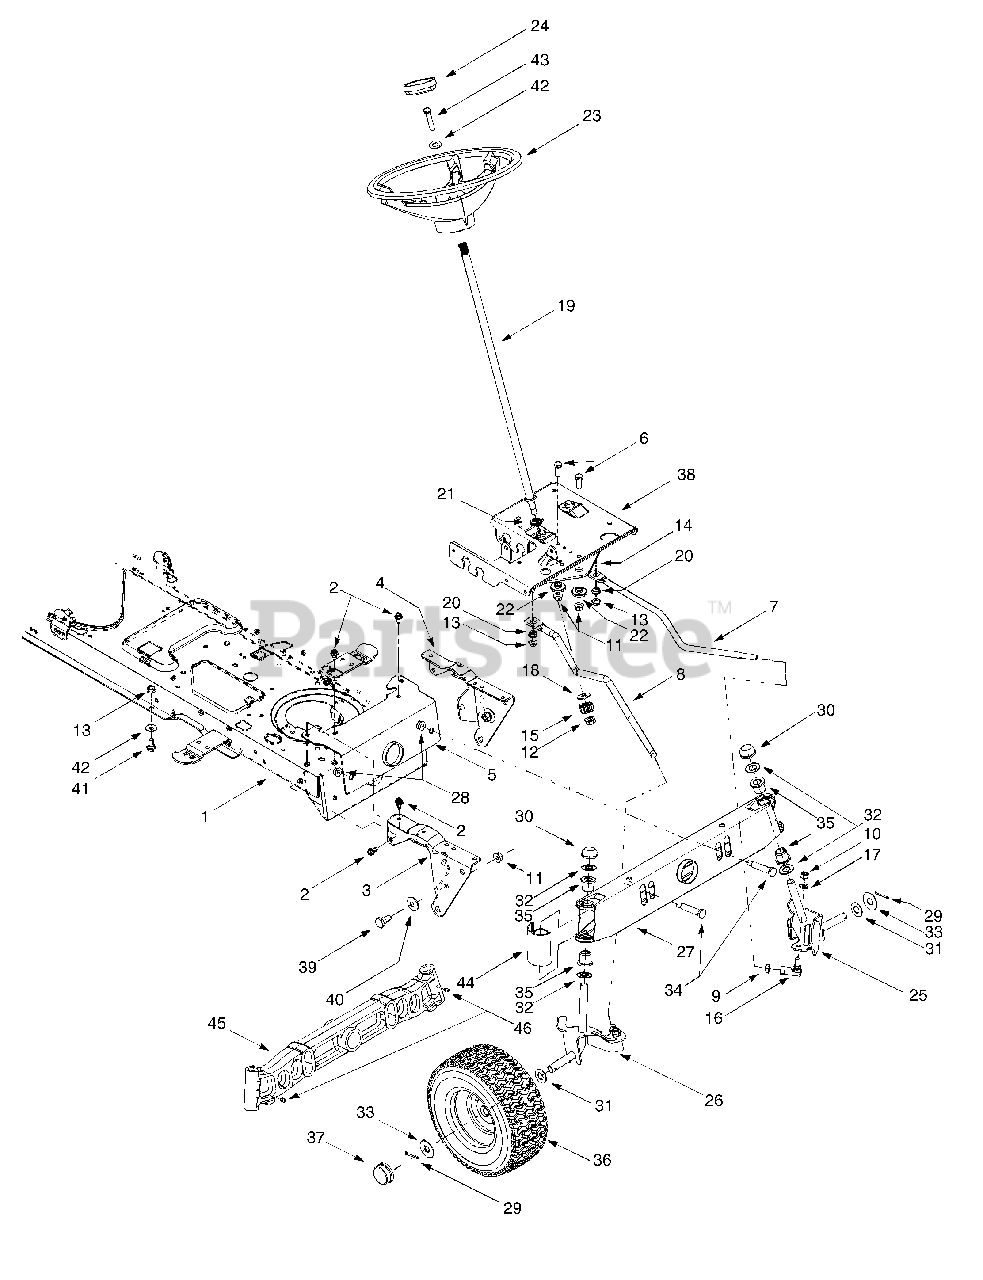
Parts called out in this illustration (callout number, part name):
6	Hex Cap Screw, 3/8-16 x 1 (Grade 5)
7	LH Drag Link
8	RH Drag Link
9	Jam Nut, 7/16-20 (Grade 2)
10	Hex Nut, 3/8-24 (Grade 2)
11	Flange Lock Nut, 3/8-16
12	Flange Lock Nut, 7/16-20
13	Flange Lock Nut, 5/16-18
14	Steering Gear, 11/90 Ratio
15	Steering Pinion Gear
16	Ball Joint, 7/16-20
17	Lock Washer, 3/8
18	Flat Washer, .51 x 1.12 x .06
19	Steering Shaft, .625 OD x 24.4
20	Plastic Bushing, .38 ID
21	Hex Flange Bearing, 5/8
22	Shoulder Spacer, .38 ID
23	Steering Wheel
24	Steering Wheel Cap
25	LH Axle Assembly, .750 Diameter
26	RH Axle Assembly, .750 Diameter
28	Flange Lock Nut, 3/8-16
29	Cotter Pin
30	Push Cap, .750
31	Flat Washer, .64 x 1.0 x .12
32	Flat Washer, .64 x 1.24 x .06
33	Flat Washer, .635 x 1.589 x .06
34	Shoulder Screw, .5 x 2.2, 3/8-16
35	Flange Bearing, .760 ID x .937 OD
37	Hub Cap
38	Steering Support Bracket
39	Shoulder Screw, 3/8-16
40	Bell Washer, .39 x 1.13 x .062
41	Shoulder Screw, .435 x .178, 5/16 x .56
42	Bell Washer, .34 x .872
43	Hex Bolt, 5/16-18 X 1
44	Pivot Bar End Cap
46	Lube Fitting, 3/16
